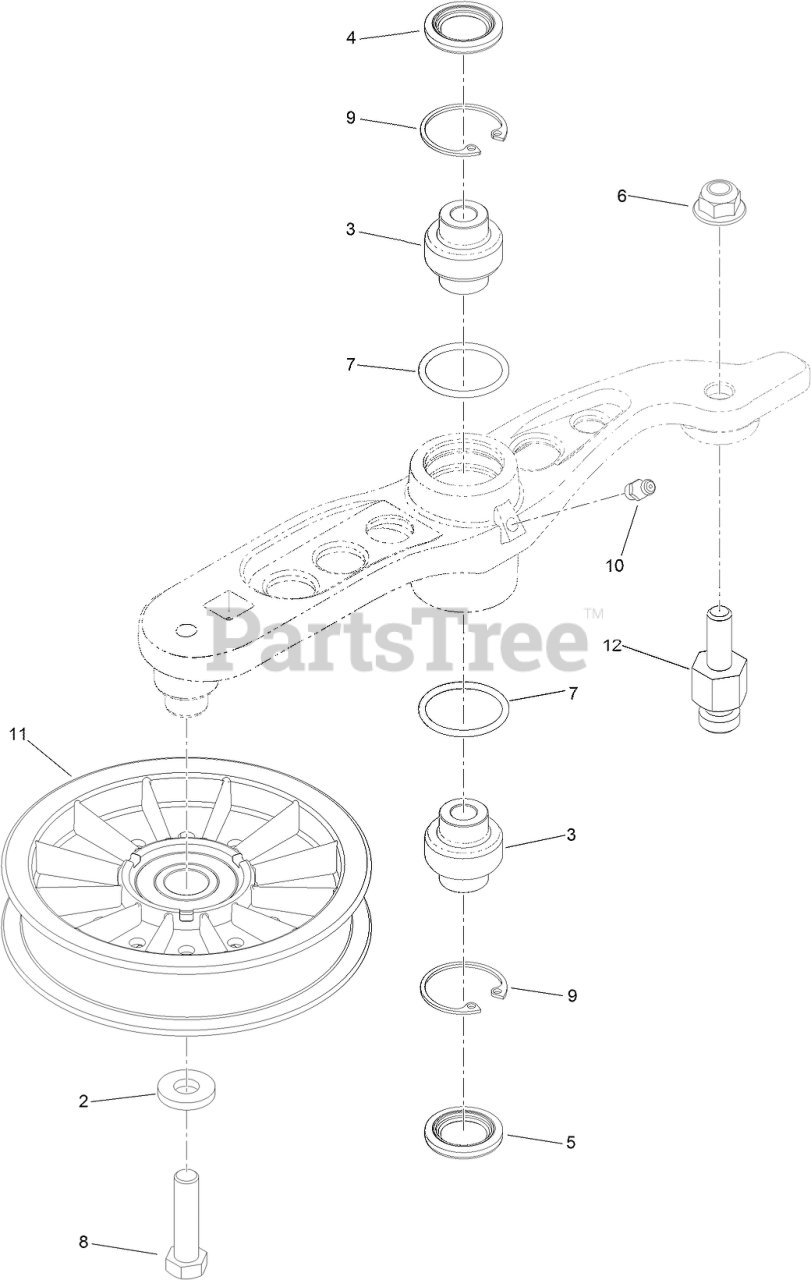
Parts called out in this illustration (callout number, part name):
3	BEARING-SPHERICAL
4	SEAL-LIP, DOUBLE
5	SEAL-LIP, SINGLE
6	Nut-Nyloc 3/8-16 Flg
8	SCREW-HH
9	RING-SNAP
10	FITTING-GREASE
11	PULLEY-IDLER
12	PIN-ANCHOR, SPRING
